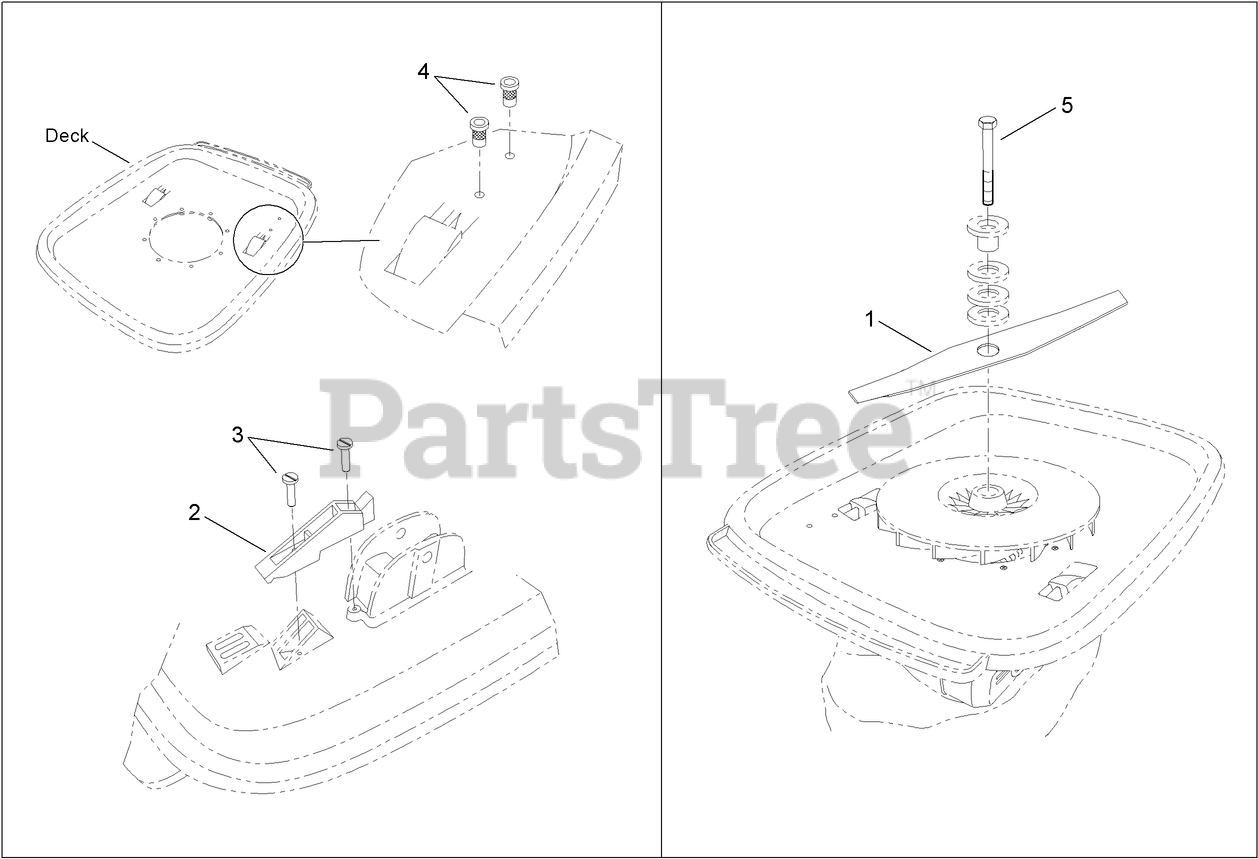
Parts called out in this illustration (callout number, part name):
1	BLADE
2	BRACKET
3	SCREW
4	INSERT
5	SCREW-SET
